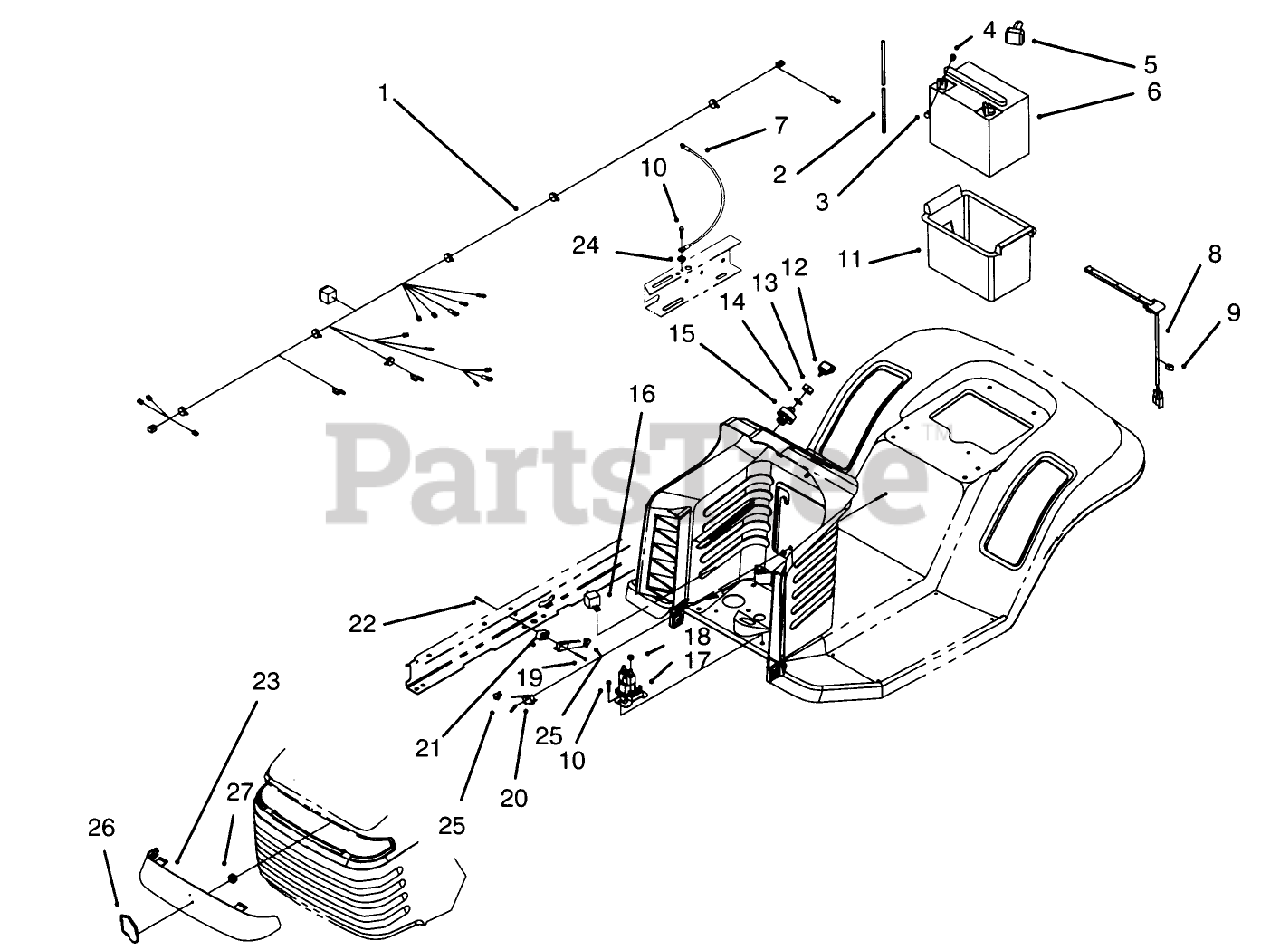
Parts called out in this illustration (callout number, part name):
1	WIRE HARNESS
2	TUBE-BATT DRAIN/80-2600
3	SCREW-HH
4	NUT-WING
5	BOOT-TERMINAL
7	WIRE ASM
8	SWITCH-SEAT
9	CLIP-RETAINER, WIRE
10	SCREW-HWH
11	BOX-BATTERY
12	KEY-IGNITION
13	NUT-HH
14	WASHER-LOCK
16	RELAY
18	NUT-KEPS
19	SCREW-HH
20	SWITCH-MICRO
21	SPACER
22	NUT-SPEED
23	LENS-HEADLIGHT
24	WASHER-LOCK/EXT
25	PLUNGER-SEAL
